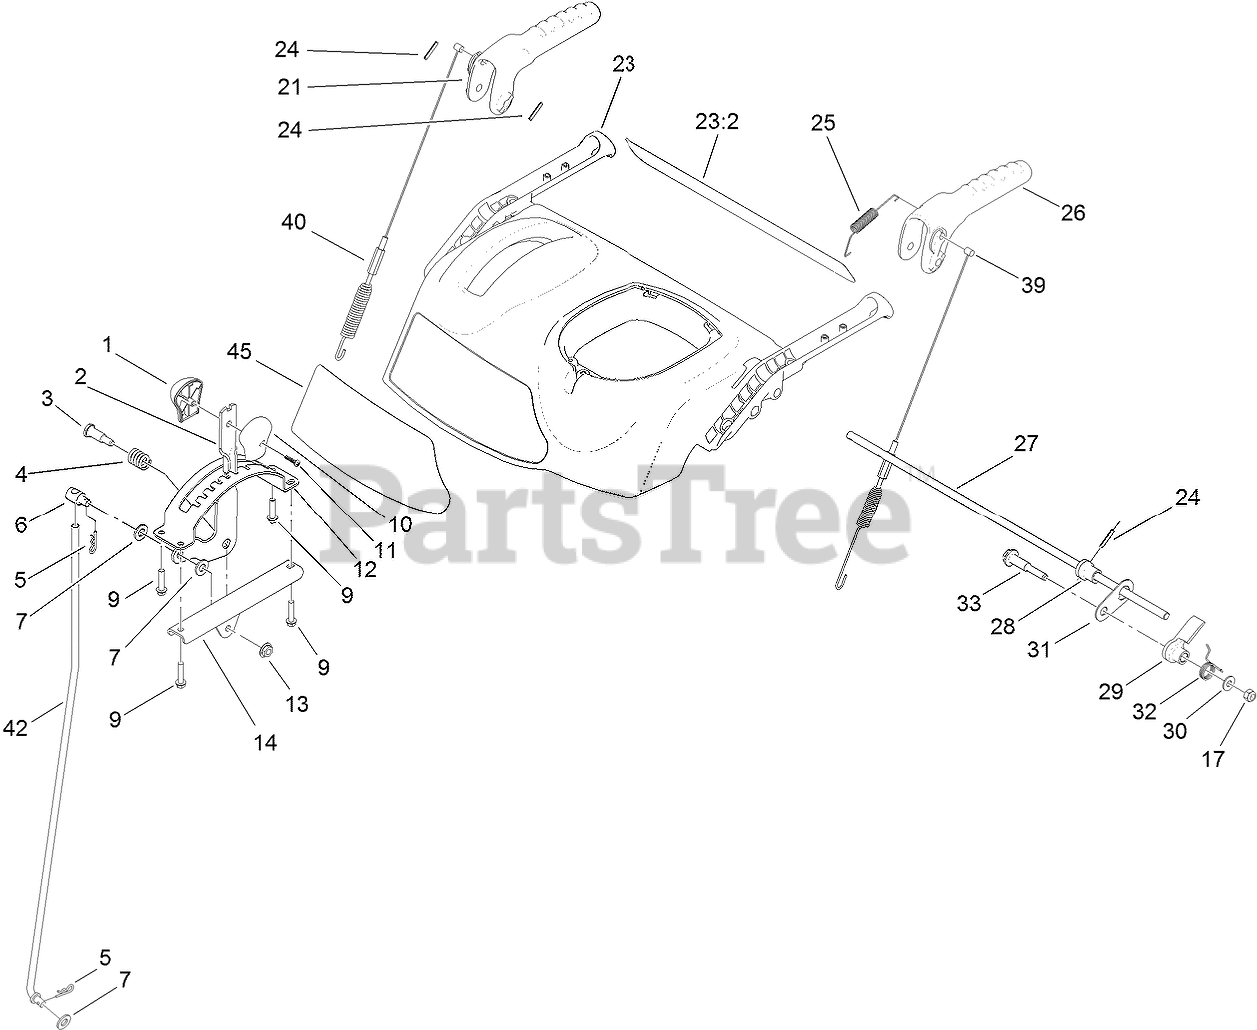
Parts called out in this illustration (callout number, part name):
1	KNOB-SHIFT, RH
2	SELECTOR-SPEED
3	SCREW-SHOULDER
4	SPRING-COMPRESSION
5	PIN-COTTER
6	TRUNNION-ROD
7	WASHER-FLAT
9	SCREW-PLASTITE
10	KNOB-SHIFT, LH
11	SCREW-PPH
12	GUIDE-SELECTOR, SPEED
13	NUT-HF
14	MOUNT-SELECTOR, SPEED
17	NUT-LOCK, NI
21	LEVER-AUGER
23	CONTROL PANEL ASM
23:2	DECAL-PANEL, CONTROL
24	PIN-SPRING
25	SPRING-TENSION
26	LEVER-TRACTION
27	ROD-LOCKOUT
28	CAM-LOCKOUT
29	LATCH-LOCKOUT
30	WASHER-FLAT
31	LINK-LOCKOUT
32	SPRING-TORSION
33	SCREW-SHOULDER
39	CABLE-TRACTION
40	CABLE-AUGER
42	ROD-SHIFT
45	DECAL-CONTROL PANEL
